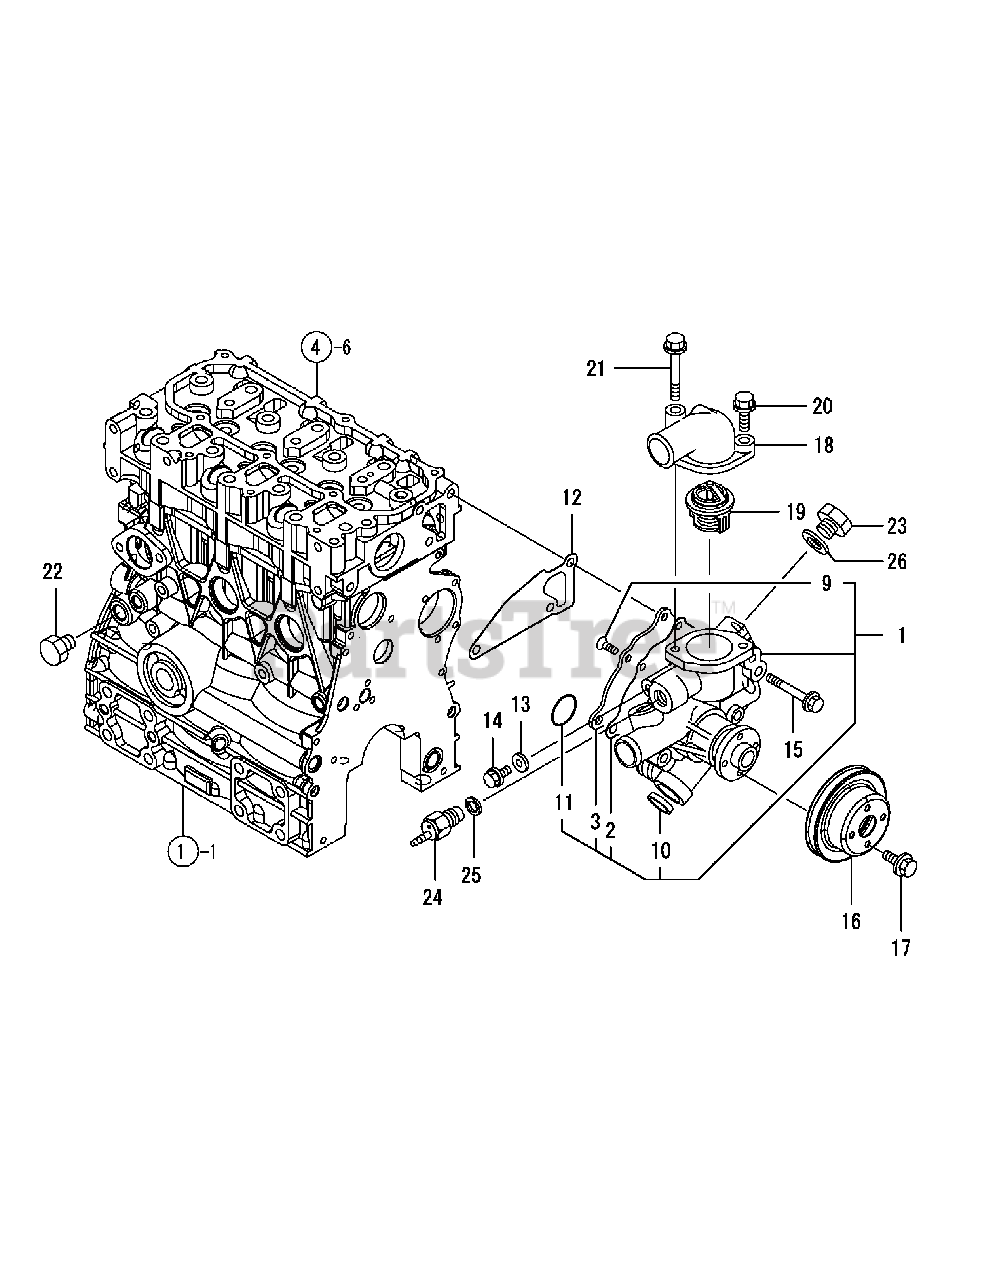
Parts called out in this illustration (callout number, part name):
1	Pump Assembly, Water
9	Screw, M 6 x 12
12	Gasket, Water Pump
13	Gasket 8, Round
14	Bolt, M 8 x 12 Plated
15	Bolt, M 8 x 50 Plated
16	V-Pulley, C.W. Pump
17	Bolt, M 6 x 12 Plated
18	Cover, Thermostat
20	Bolt, M 6 x 25 Plated
21	Bolt, M 6 x 65 Plated
24	Switch, Thermo
